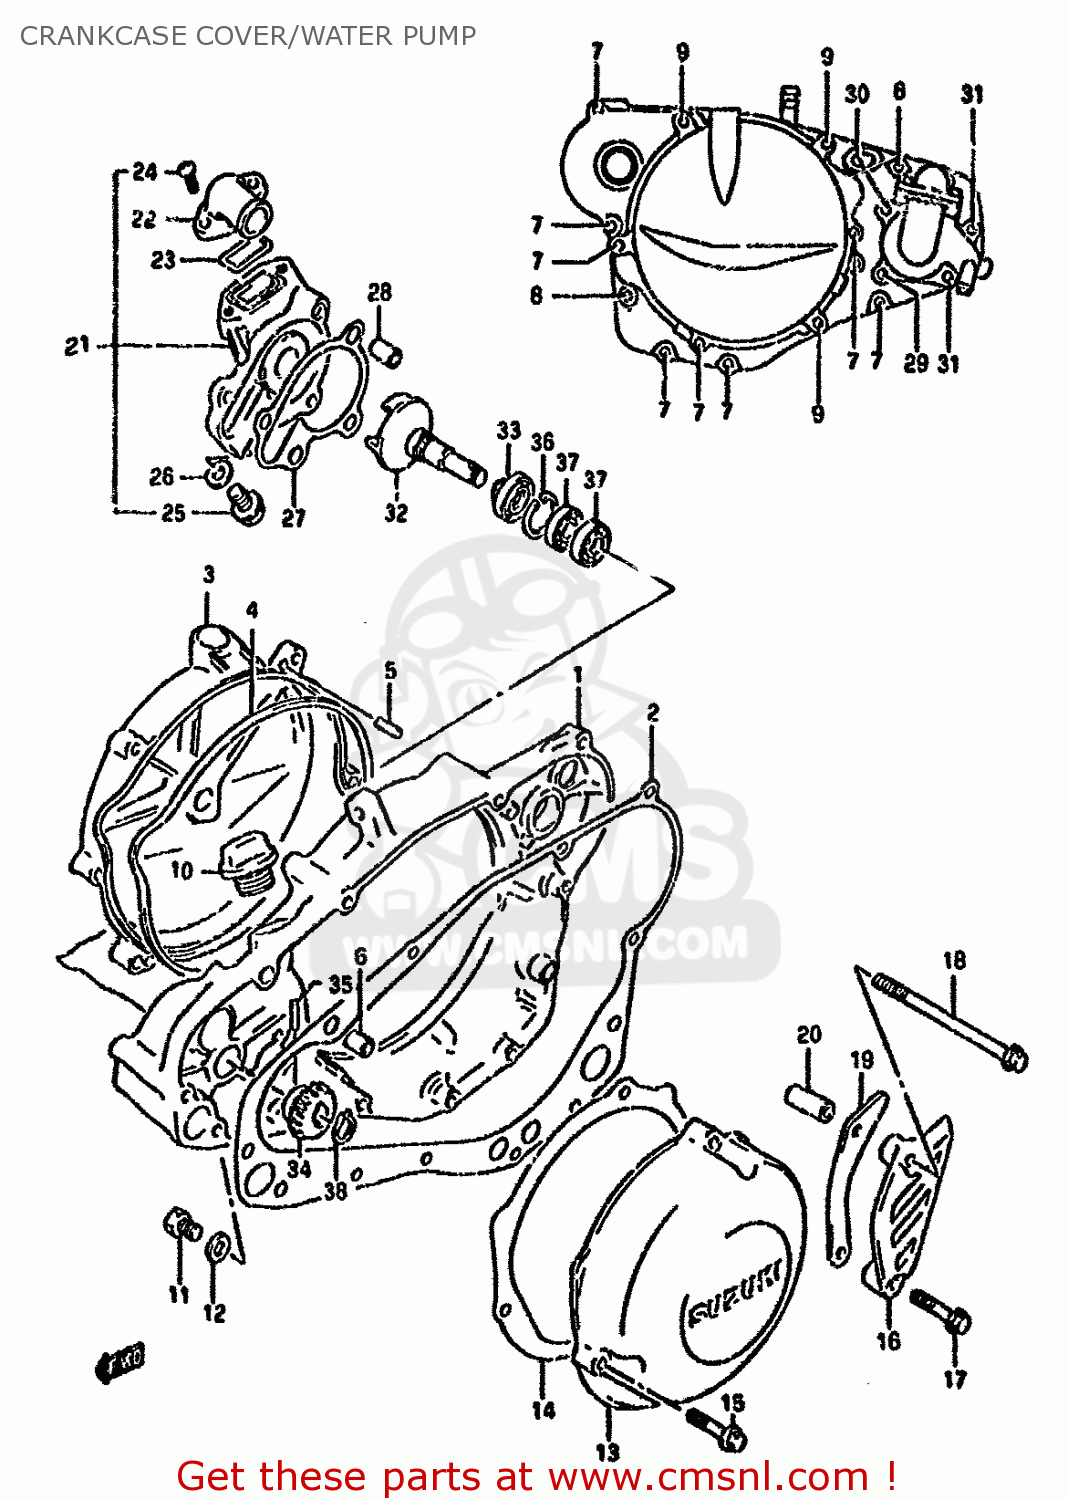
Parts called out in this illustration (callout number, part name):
1	COVER,CLUTCH
2	GASKET,CLUTCH COVER (NAS)
3	COVER,CLUTCH OUTER
4	O RING,CLUTCH COVER OUTER
5	PIN
6	PIN
7	BOLT
8	BOLT
9	BOLT
10	PLUG SET
11	SCREW(6X10)
12	GASKET(6.2X11X1).2 (NAS)
13	COVER,MAGNETO
14	GASKET,MAGNETO COVER (NAS)
15	BOLT
16	COVER,ENGINE SPROCKET
17	BOLT
18	BOLT
19	PLATE,FR CHAIN GUIDE(13T)
20	SPACER(6.5X10.5X25)
21	CASE ASSY,WATER PUMP
22	CONNECTOR
23	O RING,WATER PUMP CONNECTOR
24	SCREW
25	BOLT
26	WASHER
27	GASKET,WATER PUMP CASE (NAS)
28	PIN
29	BOLT
30	BOLT
31	BOLT
32	IMPELLER,WATER PUMP
33	SEAL,WATER PUMP OIL
34	GEAR,WATER PUMP DRIVEN
35	PIN(3X13.8)
36	CIRCLIP
37	BEARING
38	CIRCLIP,10MM
